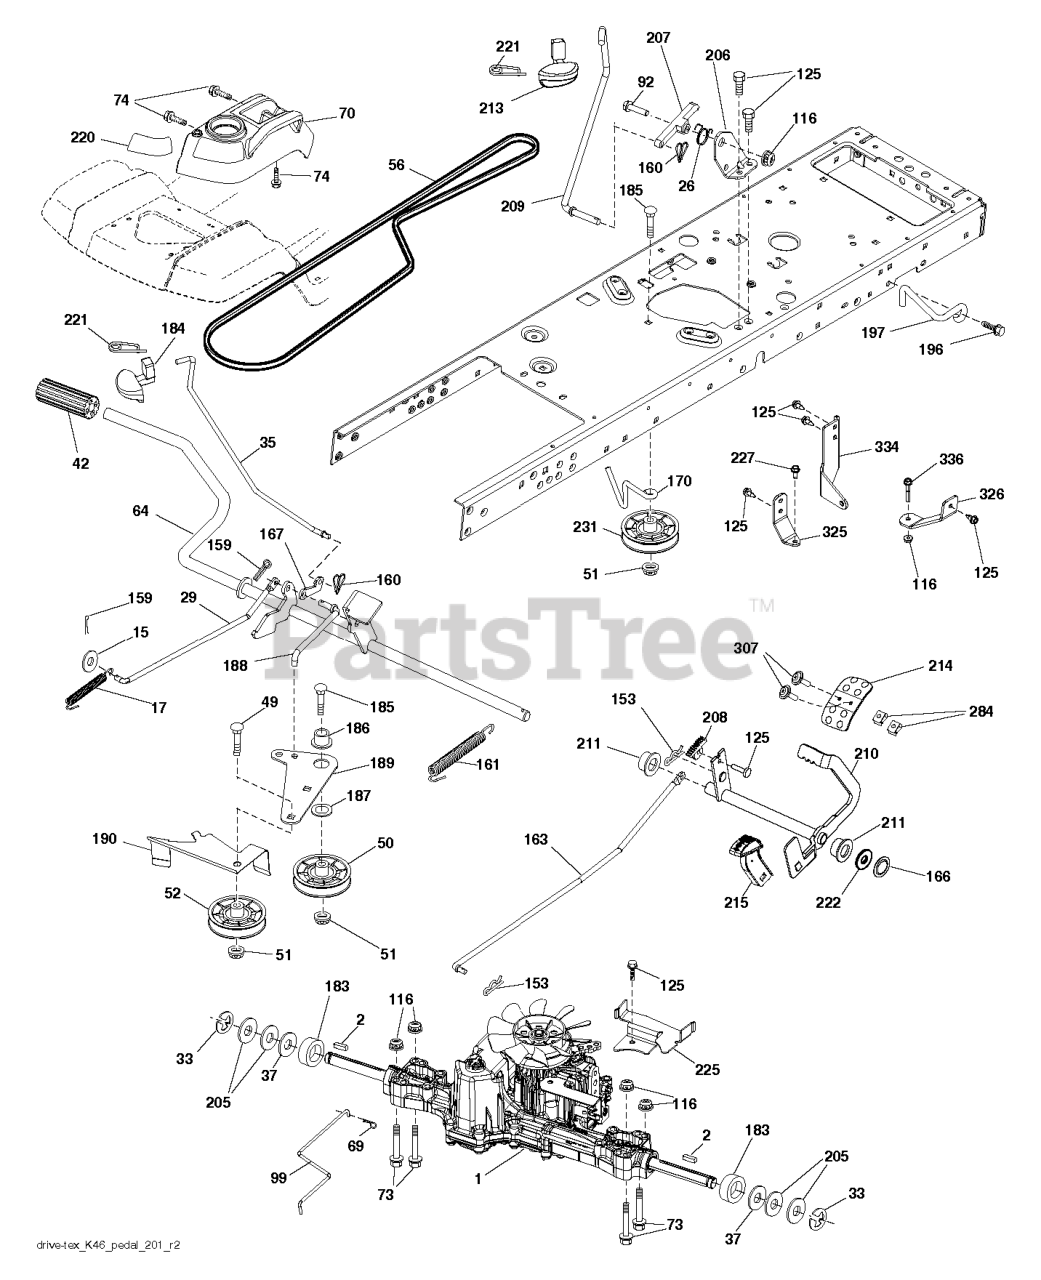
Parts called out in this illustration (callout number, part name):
2	SQUARE KEY
15	WASHER
17	SPRING.BRAKE.K46.GREEN
26	SPRING.RETURN.CRUISE
29	ROD.BRAKE.K46
35	ROD ROD.PARKINGBRAKE.GT.HUSQ/P
37	WASHER.HARDENED
42	PEDAL COVER T
50	IDLER.FLAT.910.OFFSET
51	NUT LOCK FLG 3/8-16 UNC
52	IDLER.V-GROOVE.910.OFFSET
56	V-BELT.MOWER.92.40.42/K46
64	SHAFT.ASM.PEDAL.BRK.CNTR
69	HAIRPIN.SOFT.ZINC.059X1.125
70	CONSOLE.ASM.RH.GT.FC.HUSQ
73	BOLT
74	SCREW.HI-LO.CONSOLE
92	BOLT
99	ARM.PIVOTING.TCRD.GEN2.5.BAGGE
116	NUT LOCK HEX FLANGE 5/16-18
125	SCREW
153	RETAINER M
159	COTTER PIN
160	RETAINER CLIP
161	SPRING, RETURN LT
163	ROD.CONTROL.K57R.K46
166	NUT.PUSH.625
167	LATCH.BRAKE.SPRING
170	KEEPER.CENTER SPAN.1.688
183	SPACER AXLE
184	HANDLE.PARKING.BRAKE.H (BLK)
186	SPACER.RETAINER
187	WASHER 12/32X2X10GA
188	LINK.CLUTCH.GROUND DRIVE.LONG
189	BELLCRANK.GROUND.DRIVE.TEX.
190	KEEPER.BELLCRANK.DRIVE
196	SCREW 3/8-16X1
197	BRKT.42.FCS.CLUTCH.ANTIROTATIO
206	BRACKET.MOUNT.CRUISE.LATCH
207	LATCH.CONTROL.CRUISE.TEX
208	GEAR.SECTOR.CONTROL.CR
209	ROD ROD.CRUISECONTROL.GT.HUSQ/
210	ROCKER.ASM.PEDAL.CONTR
211	BEARING.NYLON
213	KNOB.CONTROL.CRUSIE.HU
214	PEDAL.FORWARD.HUSQVARNA.DEALER
215	PEDAL.COVER.REVERSE.CRD.X428BK
220	REFLECTOR.RH.TEX GT
221	RETAINER.SPRING.CLIP.H
222	WASHER 21/32 X 1-1/4 X 10 GA.
225	KEEPER.BELT.TRANSAXLE.K46
227	SCREW.THDROL.5/16-18X3/4.TTY
231	IDLER.V-GROOVE.1.688.OFFSET
284	NUT.U-CHNL.1/4-20.550DP.350PNL
307	SCREW.MACHINE.CR.1/4-20
325	TORQUE.STRAP.K46.LT.LH
326	BRCKT.PNT.TRQ.STP.46.18TIRE.RH
334	SWAY.ROD.BRACKET.K46.X431
336	BOLT.5/16-18X1-3/4.FLANGED.HEX
